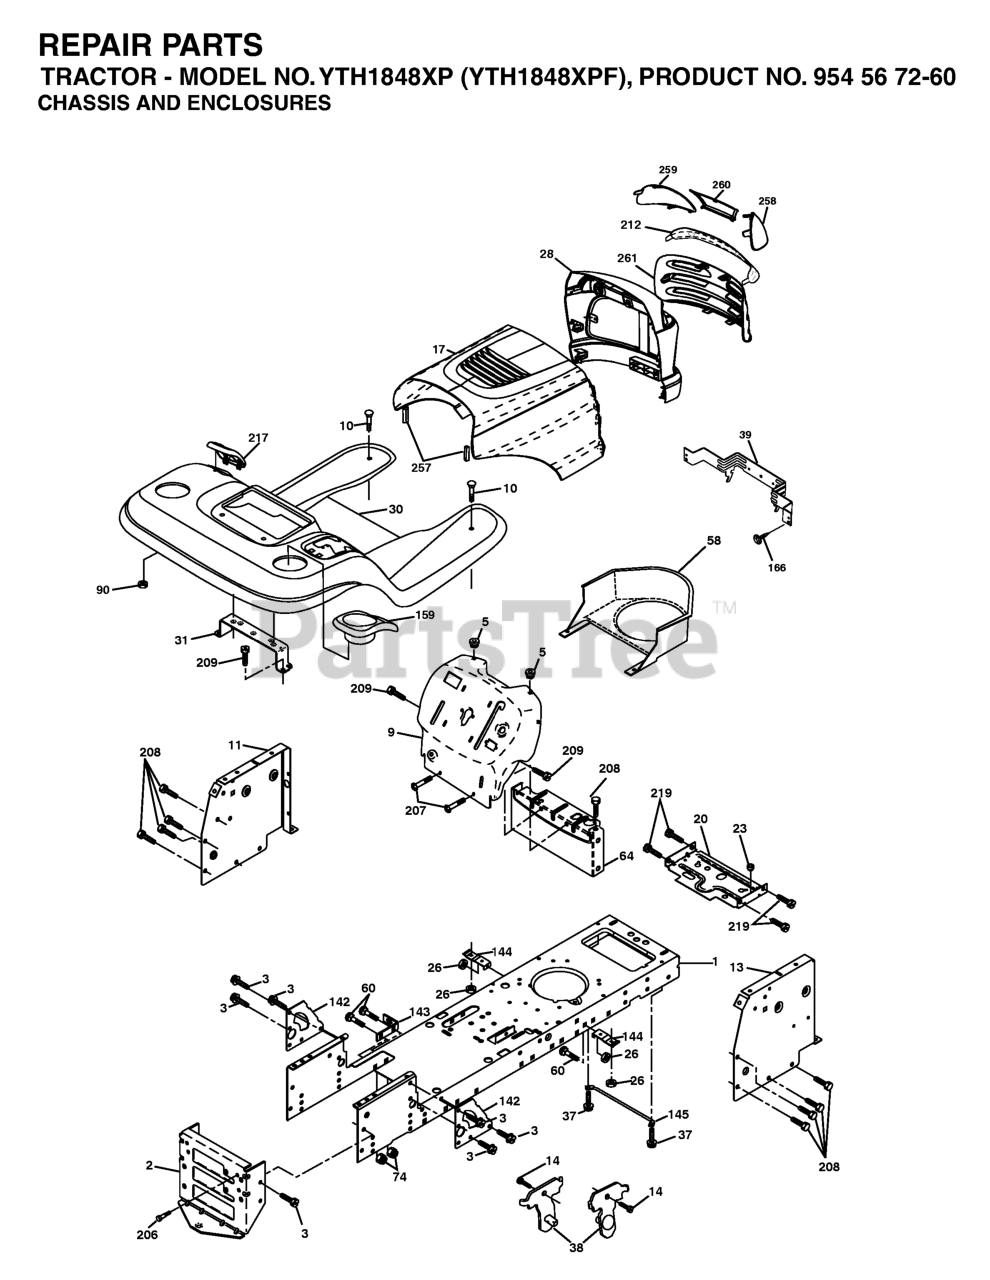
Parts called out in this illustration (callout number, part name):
1	CHASSIS STAMPING
2	DRAWBAR, 12GA
3	SCREW 3/8-16X3/4
5	BUMPER.RUBBER.HOOD
9	DASH SLKSCR
10	BOLT D
11	PANEL.DASH.LH.LTX
13	PANEL ASM, DASH RH
17	HOOD
20	PLATE MTG.BATTERY/FUEL TANK
23	BUSHING.SNAP.NYL.BLK.
26	NUT
30	FENDER
31	BRACKET.SUPPORT.FENDER
37	Screw 5/16-18 x 1/2 Hex, Self Tapping 5/16-18 x 1/2
38	BRACKET.ASM.PIVOT.MOWER.REAR
39	BRACKET PIVOT LASER
60	Bolt - Rd. Hd. Sq. Neckiage 3/8 16 x 3/4
64	DASH LOWER
90	NUT.PUSH.3/16
142	PLATE REINFORCEMENT
143	BRACKET, SWAY BAR
144	BRKT, FOOT REST
145	ROD PIVOT CHASSIS/HOOD
159	GREY CUP HOLDER
166	SCREW
206	SHOULDER BOLT 5/16-18TT
207	SCREW, 5/16-18 X 1/2
208	SCREW 3/8-16X1/2
209	SCREW, 3/8-16X3/4
212	INSERT.LENS.REFLECTIVE
217	CONSOLE FUEL WINDOW
219	SCREW
257	BUMPER.HOOD.LARGE.1.75"
258	LENS LH
259	LENS LH
260	COVER.LENS.HUSQ.( HAVE GRAY)
261	INSERT GRILLE
